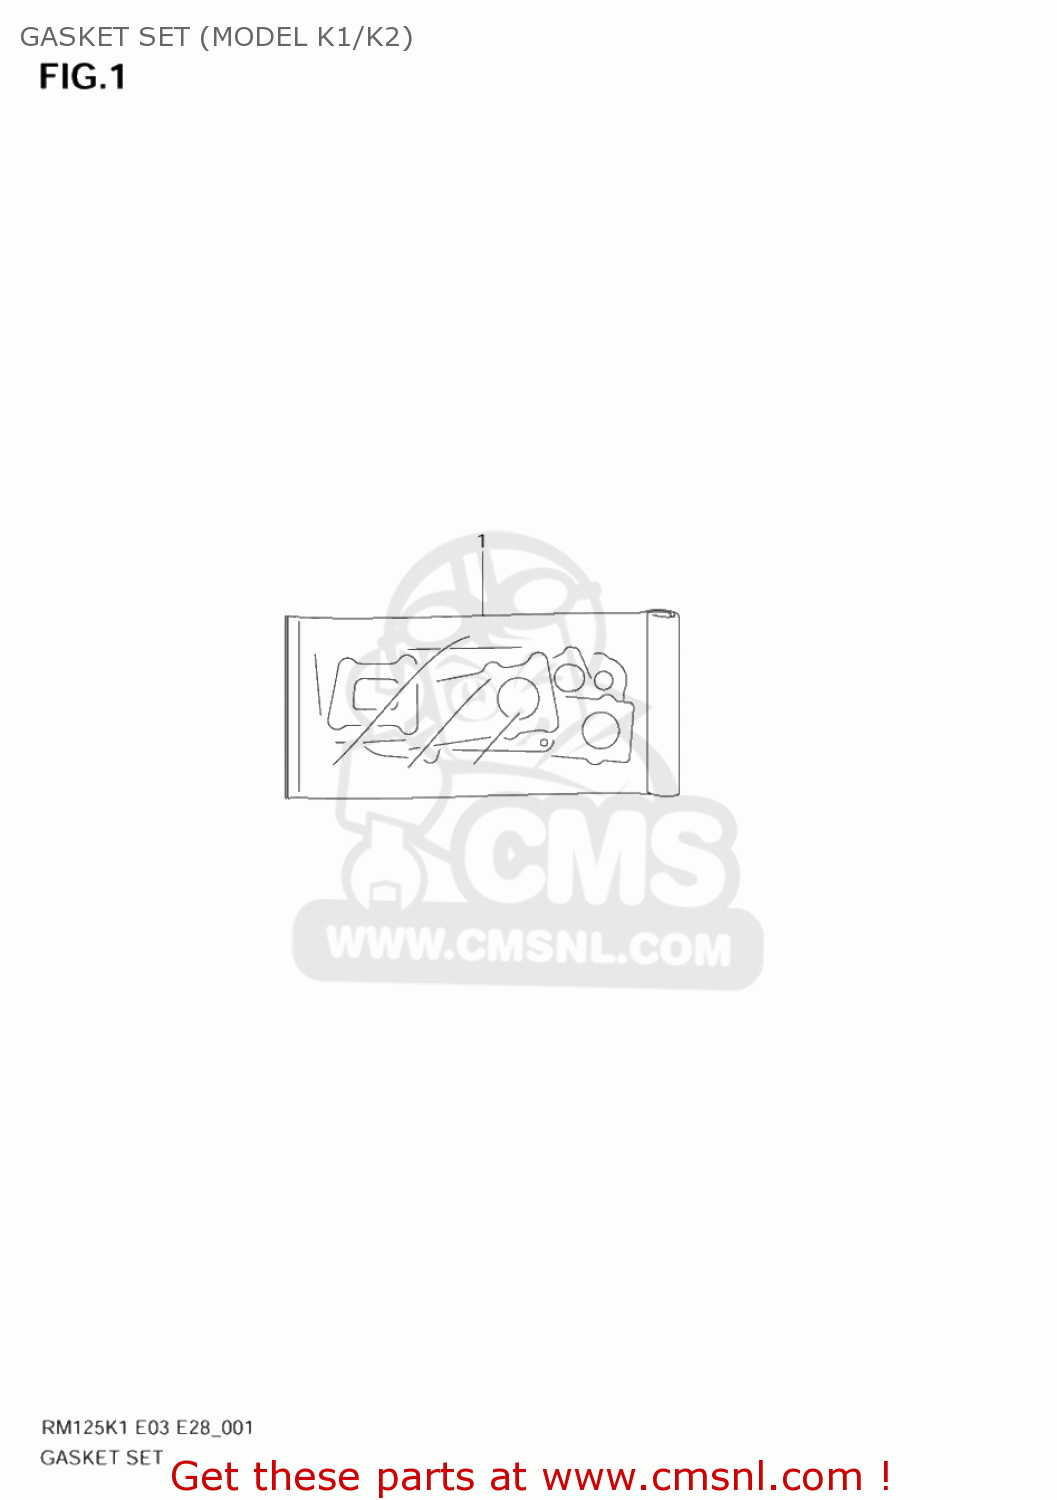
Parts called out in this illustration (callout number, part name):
1	GASKET SET (NAS)
2	O RING,CYLINDER HEAD NO.1
3	O RING,CYLINDER HEAD NO.2
4	GASKET,CYLINDER COVER NO.1 (NAS)
5	GASKET,CYL COVER NO.2
6	GASKET,CYLINDER (NAS)
7	GASKET,CRANKCASE (NAS)
8	GASKET,CLUTCH COVER (NAS)
9	GASKET,MAGNETO COVER
10	O RING,CLUTCH COVER OUTER
11	O RING,EXHAUST PIPE
12	O RING(D:1.9,ID:22.6)
